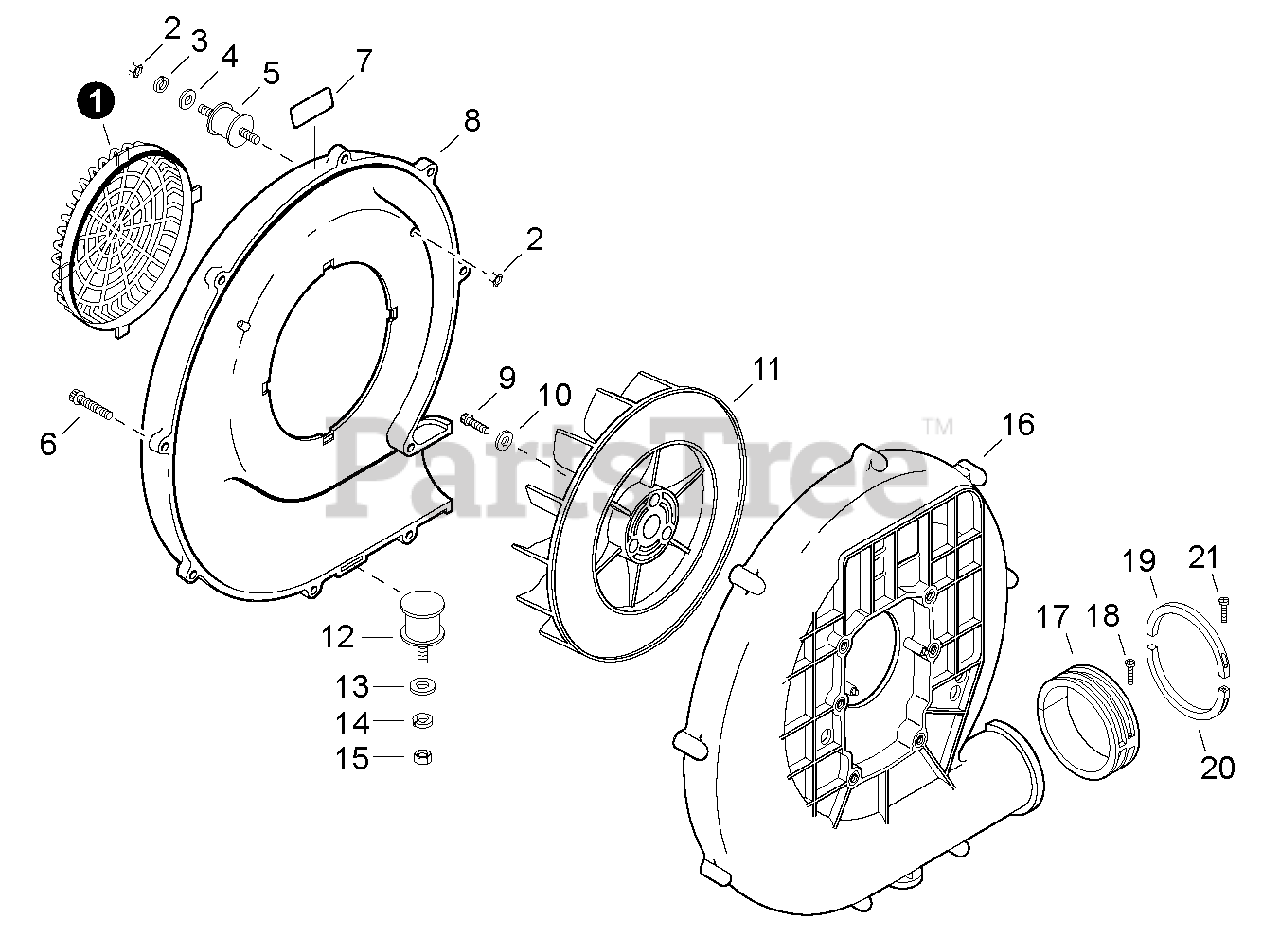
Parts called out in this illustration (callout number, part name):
1	COVER, INTAKE
2	NUT M5
3	WASHER, SPRING 5
4	WASHER 5
5	CUSHION 5
6	BOLT, TAPPING 5
7	LABEL, NOISE
8	COVER, FAN
9	BOLT 6
10	WASHER 6
11	FAN, BLOWER
12	CUSHION 6
13	COLLAR Ø18ר6.4×L2
14	WASHER, SPRING 6
15	NUT, HEX M6
16	CASE, FAN
17	SLEEVE
18	SCREW, TAPPING
19	RETAINING RING (A)
20	RETAINING RING (B)
21	SCREW
